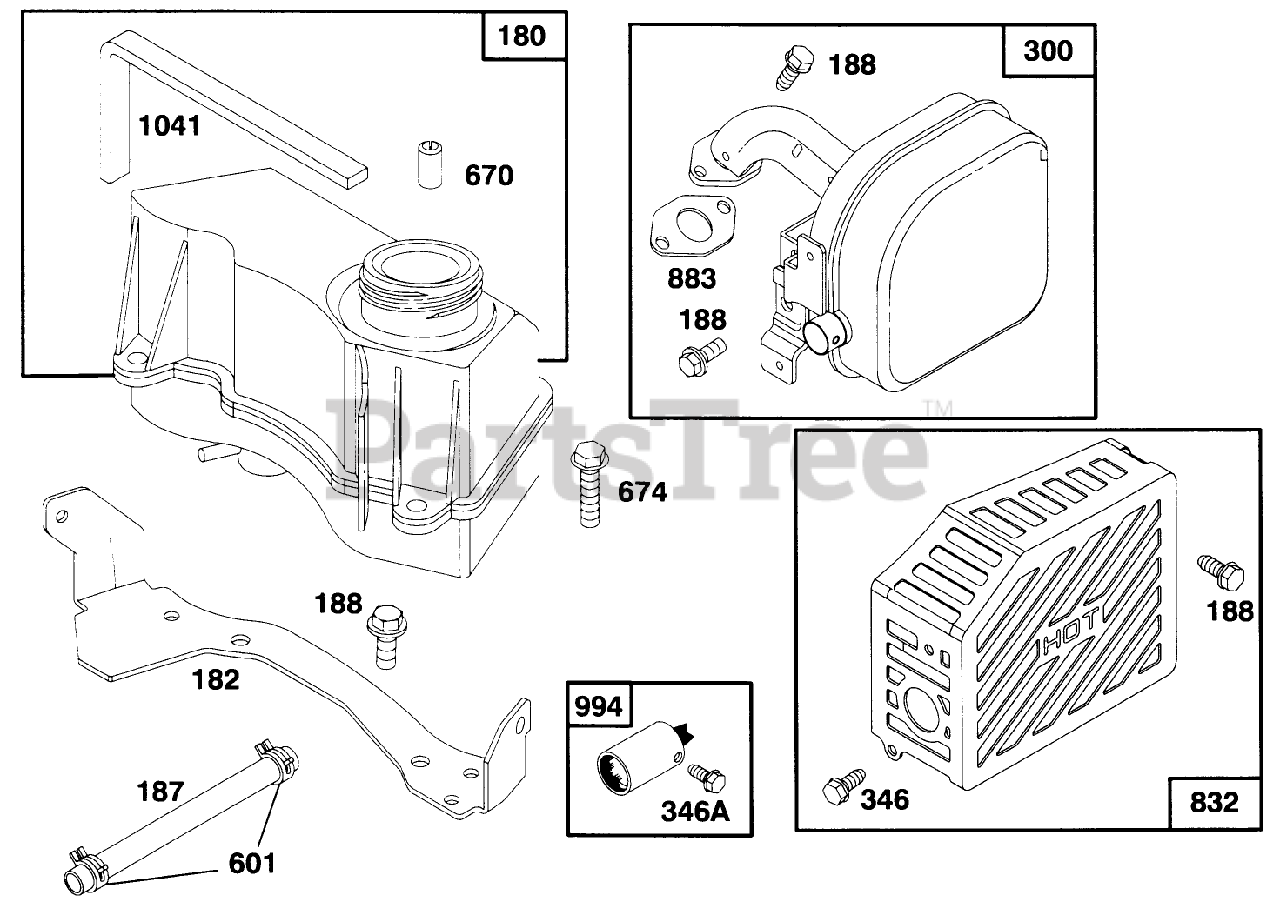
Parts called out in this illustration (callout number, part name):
300	MUFFLER - EXHAUST
601	CLAMP - CL PIPE
670	SPACER
674	SCREW - HEX HEAD
